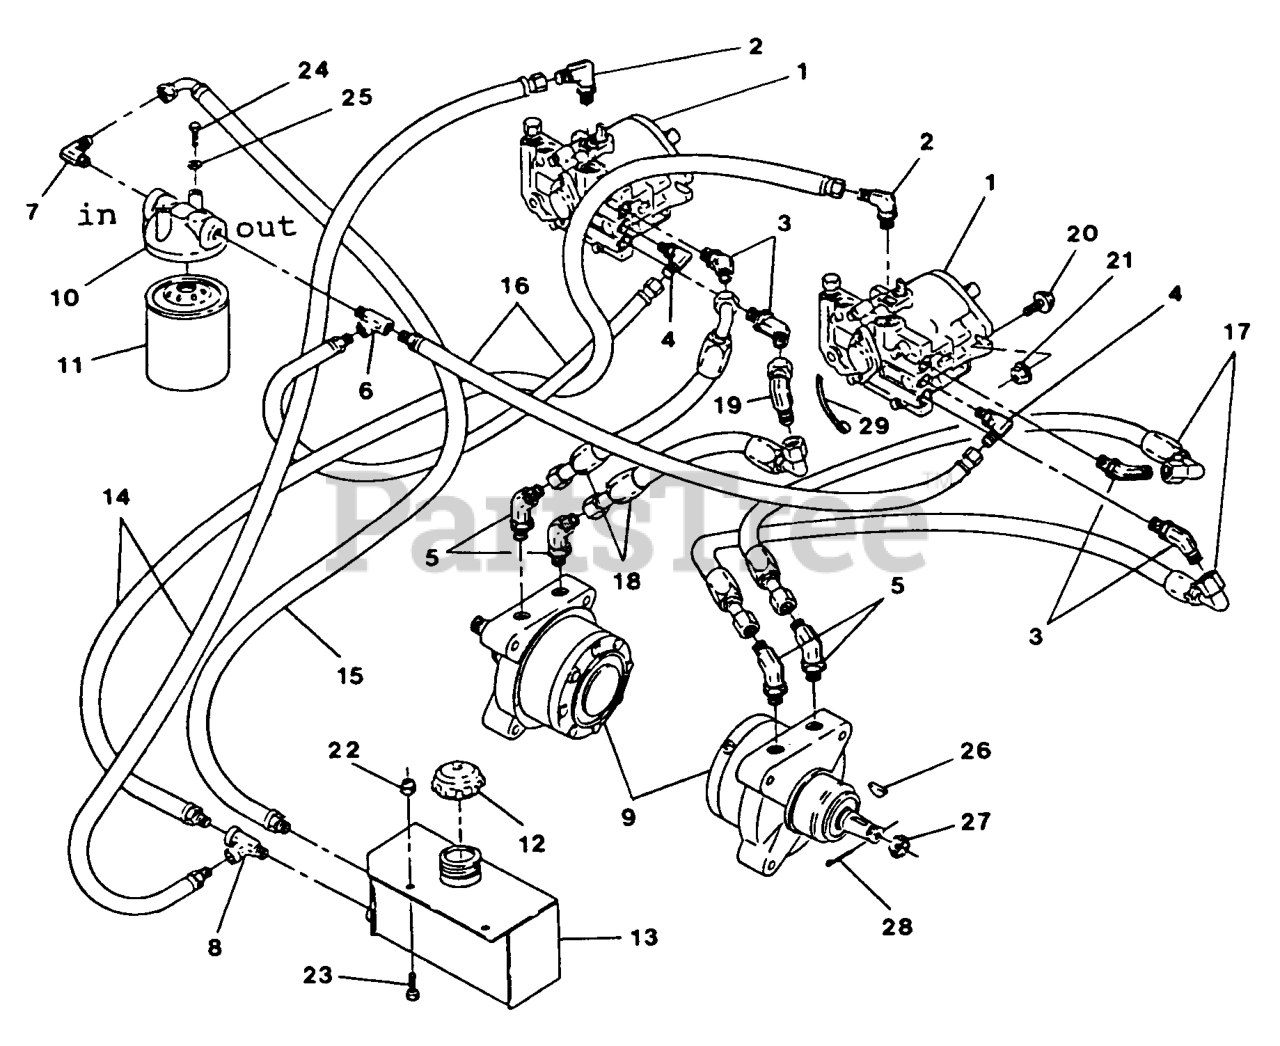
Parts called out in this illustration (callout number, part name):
2	FITTING-90 DEG
4	ELBOW,90 DEGREE
5	FITTING,45 DEGREE
10	FILTER-HEAD
25	WASHER-LOCK
27	NUT-HH
28	PIN-COTTER
29	TIE-PLASTIC
